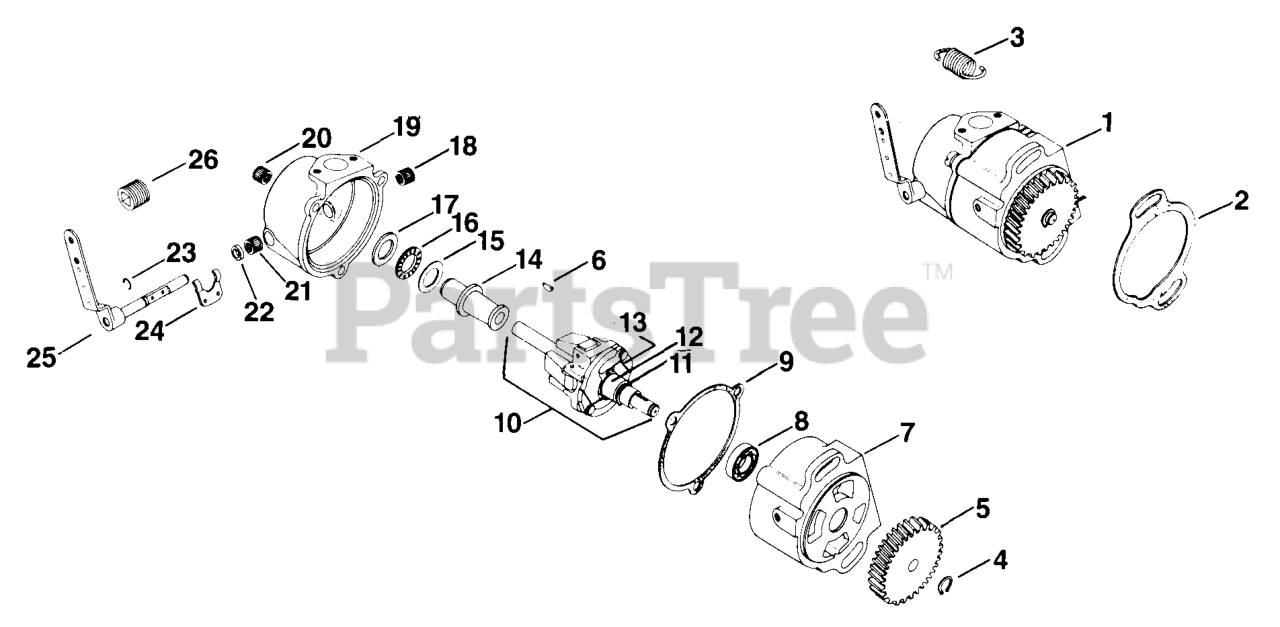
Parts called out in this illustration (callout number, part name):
1	KIT, GOVERNOR - DISCONTINUED
3	SPRING - DISCONTINUED
5	GEAR - USE 48 043 11
6	KEY, 3/32" X 3/8"
8	BEARING - (#DSC)
9	GASKET - DISCONTINUED
10	SHAFT - (#DSC)
12	CAM - (#DSC)
13	SPRING - DISCONTINUED
14	KIT, THRUST SLEEVE
16	BEARING - DISCONTINUED
19	COVER - DISCONTINUED
22	SEAL - (#DSC)
26	PLUG, CTSK PIPE 1/8" USE 25 139 60-S
